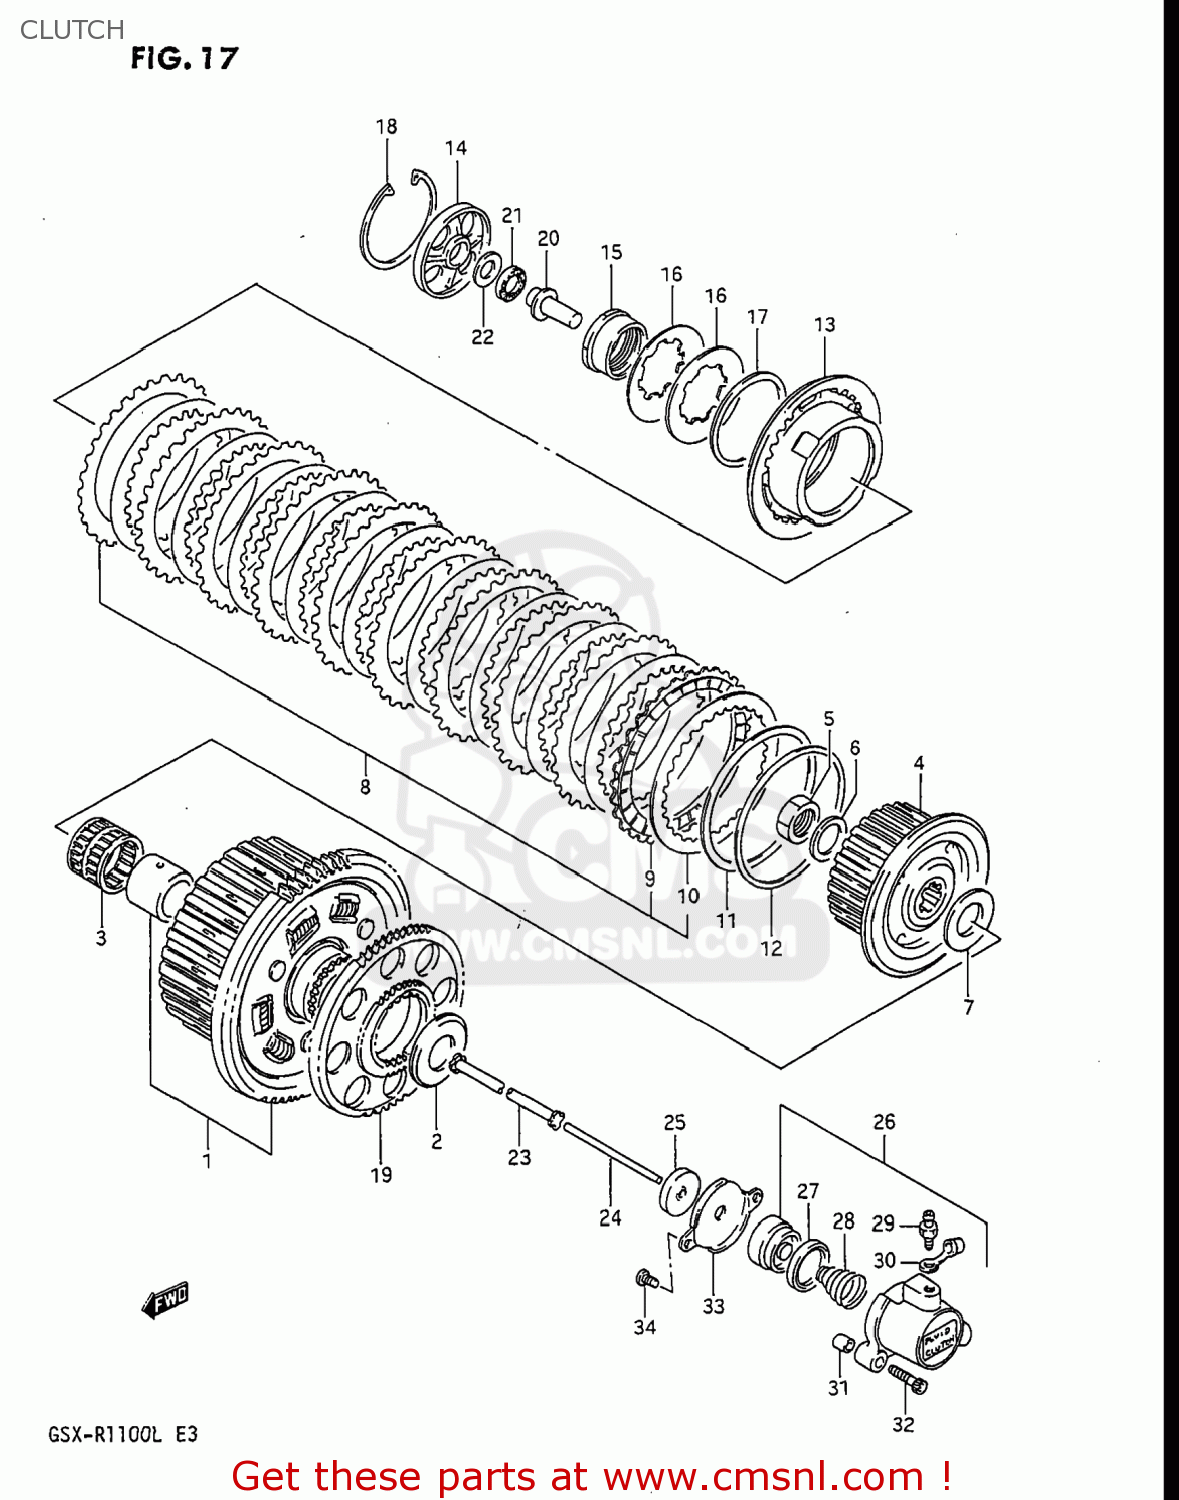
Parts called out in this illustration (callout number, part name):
1	GEAR ASSEMBLY,PRIMARY DRIVE
2	WASHER(25X54X2.5)
3	BEARING(35X40X35.8)
4	HUB,CLUTCH SLEEVE
5	NUT
6	WASHER
7	WASHER(25X50X2.5)
8	PLATE ASSEMBLY,CLUTCH
9	PLATE,CLUTCH DRIVE NO.1 (NAS)
10	PLATE,CLUTCH DRIVEN (NAS)
11	WASHER
12	SEAT,CL SLEEVE HUB WAVE WASHER
13	DISC,CLUTCH PRESSURE
14	LIFTER,CLUTCH PRESSURE DISC
15	HOLDER,CLUTCH SPRING
16	WASHER
17	SEAT,CLUTCH SPRING
18	CIRCLIP
19	GEAR,GENERATOR DRIVE
20	PIECE,CLUTCH PUSH
21	BEARING(15X28X2)
22	WASHER
23	ROD,CLUTCH
24	ROD,CLUTCH PUSH
25	SEAL,OIL(6X34X5.5)
26	CYLINDER,CLUTCH RELEASE
27	CUP
28	SPRING,CLUTCH CYLINDER
29	BLEEDER
30	CAP,BLEEDER
31	PIN
32	BOLT
33	PLATE,CLUTCH PUSH ROD
34	SCREW
